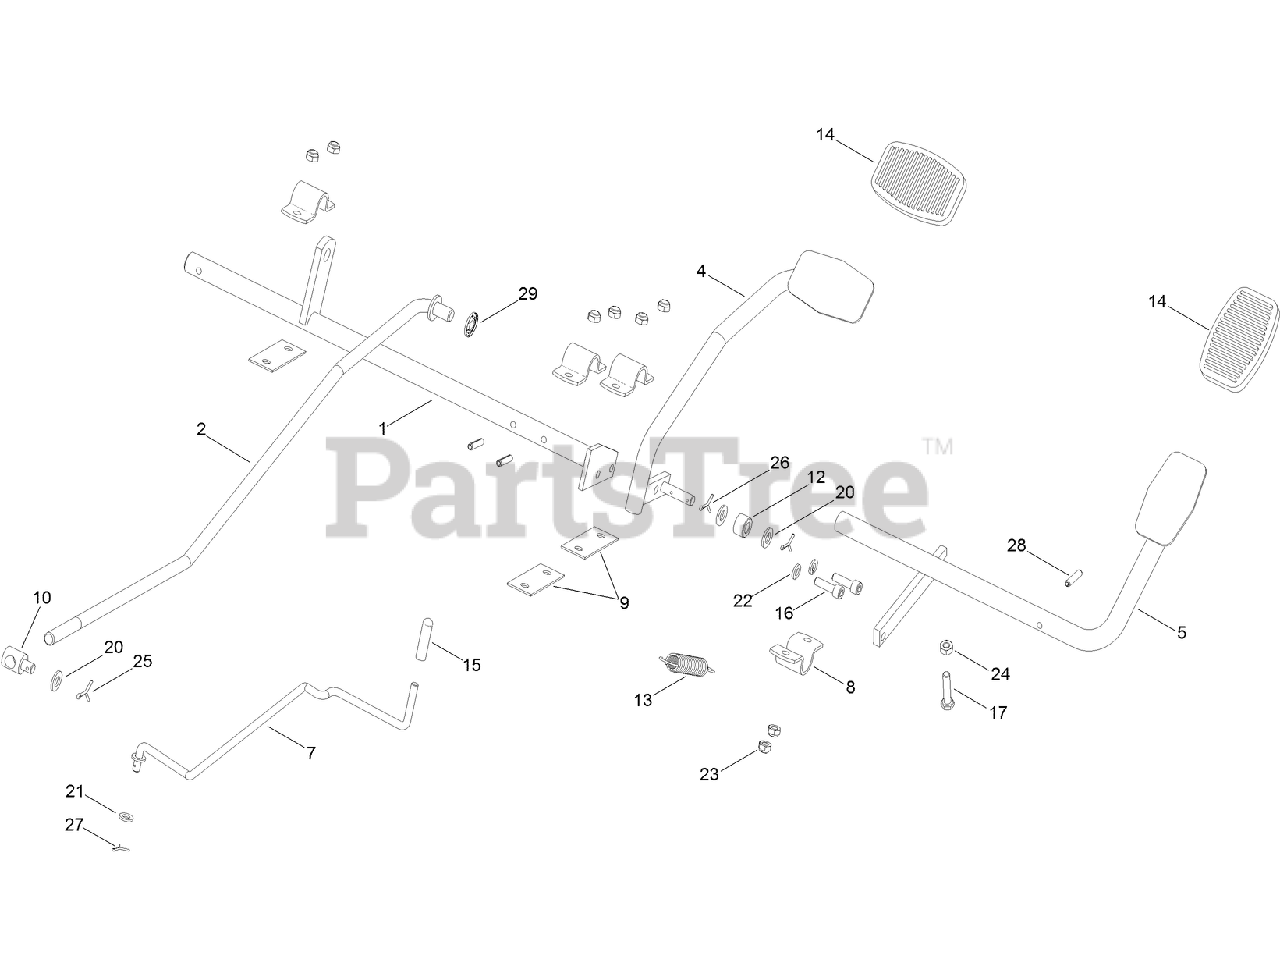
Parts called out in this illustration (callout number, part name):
1	SHAFT-PIVOT
2	ROD-LINKAGE
4	PEDAL-TRAVEL, FORWARD
5	PEDAL-TRAVEL, REVERSE
7	ROD-LEVER, BYPASS
9	SPACER
12	Roller
13	SPRING
14	PAD-PEDAL
15	CAP-BYPASS LEVER, HYDRO
17	SCREW-HH
20	WASHER-PLAIN
21	WASHER
22	WASHER-SPRING
23	NUT-LOCK
24	NUT-HEX
25	PIN-COTTER
26	PIN-COTTER
27	PIN-COTTER
28	PIN-SPRING
29	WASHER-M10
